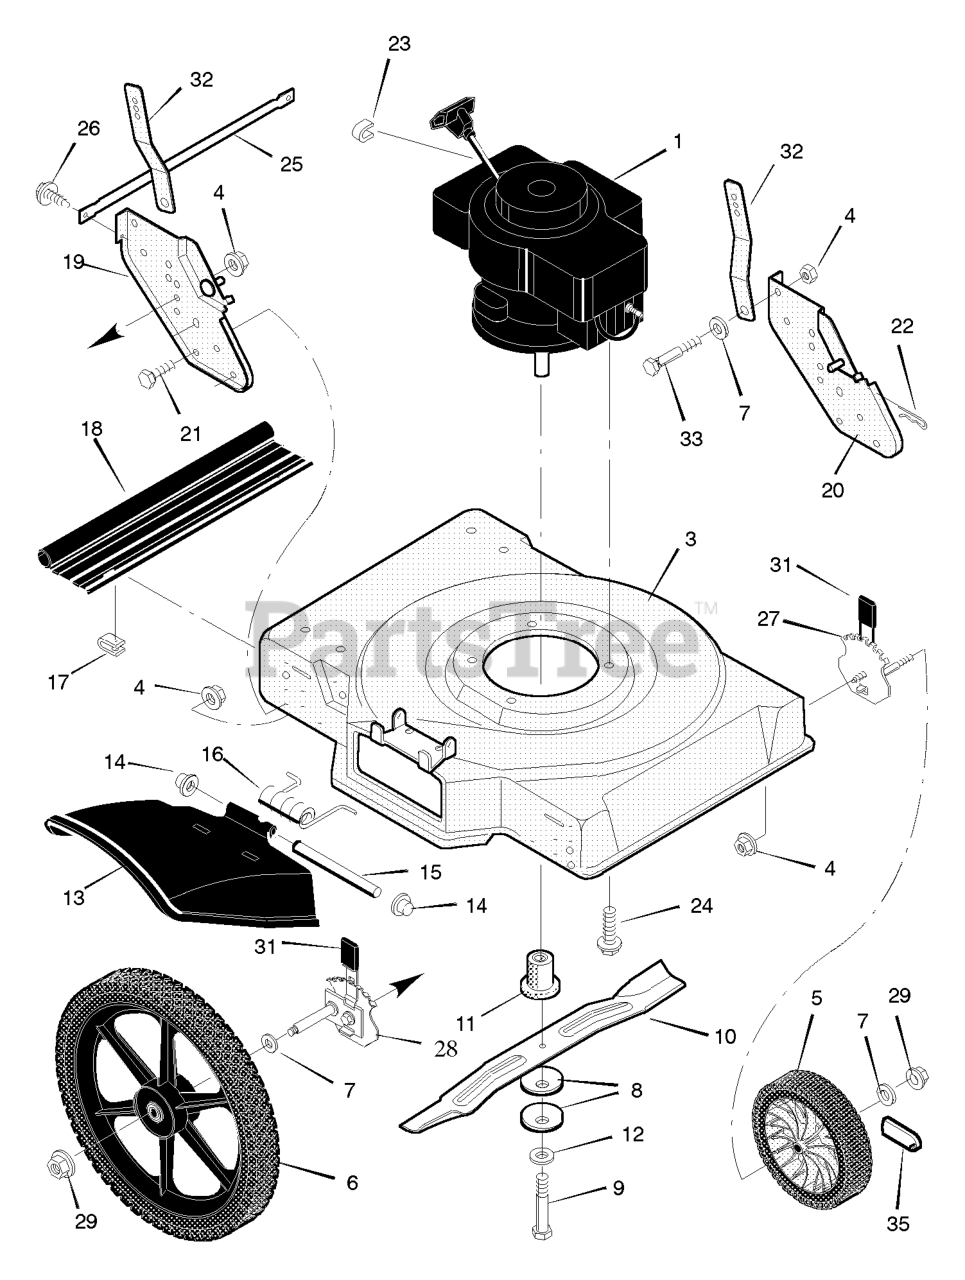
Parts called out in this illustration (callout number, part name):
1	Engine *
3	Housing
4	Nut, Hex
5	WHEEL & TIRE ASSEMBLY, White, 8"
6	Wheel and Tire, Rear (White)
8	Washer, Blade
9	Bolt, Hex
10	Blade - Standard
11	Blade Adapter
13	Deflector, Chute
14	Push On Cap
15	Pin, Pivot
17	Retainer
18	Deflector, Rear
19	Bracket, Right Wheel
20	Bracket, Left Wheel
21	Bolt, Hex
22	Pin, Hair
23	Stop, Rope
24	Bolt, Engine
27	Height Adjuster, Front
28	Height Adjuster, Rear
29	Locknut
32	Support, Handle
33	Bolt, Shoulder
35	Hub Cap
